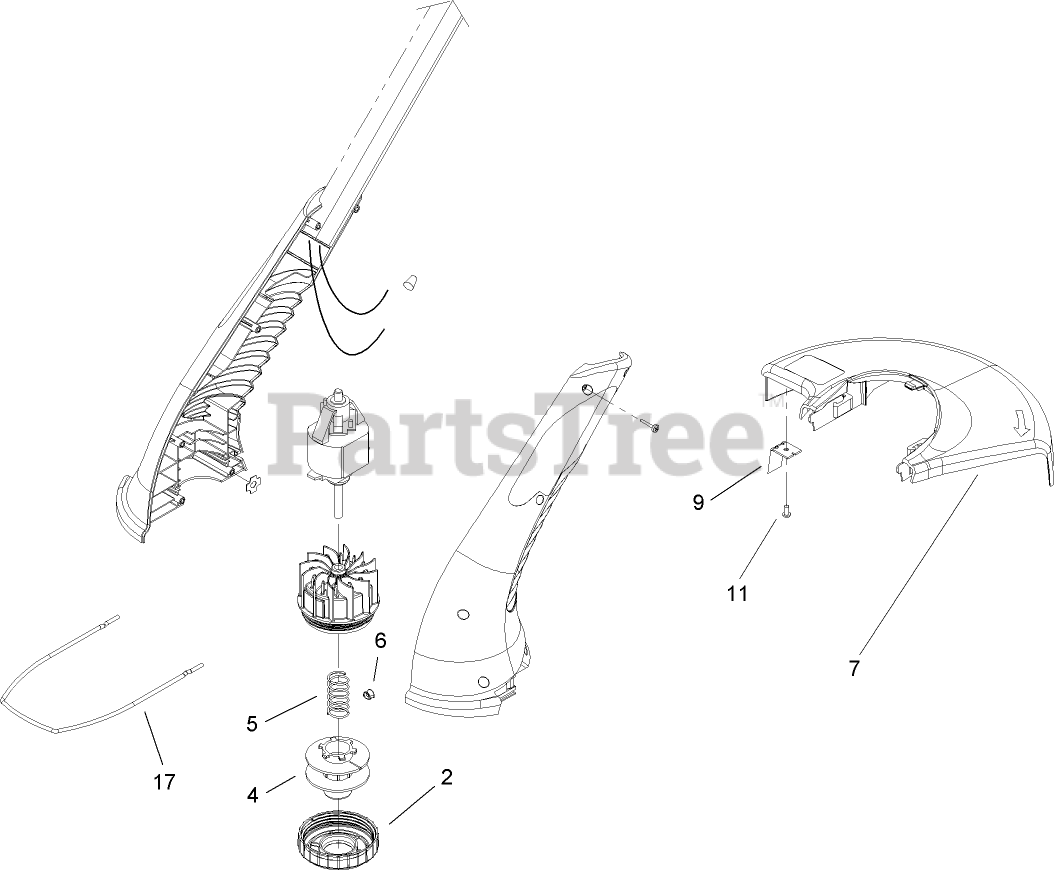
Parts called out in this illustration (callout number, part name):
2	CAP-DRUM
4	.065 SPOOL ASM
4:1	SPOOL-LARGE
5	SPRING-EXTENSION
6	EYELET-GUIDE
7	SHIELD-12 INCH
9	BLADE-CUTOFF
11	SCREW-PPH
